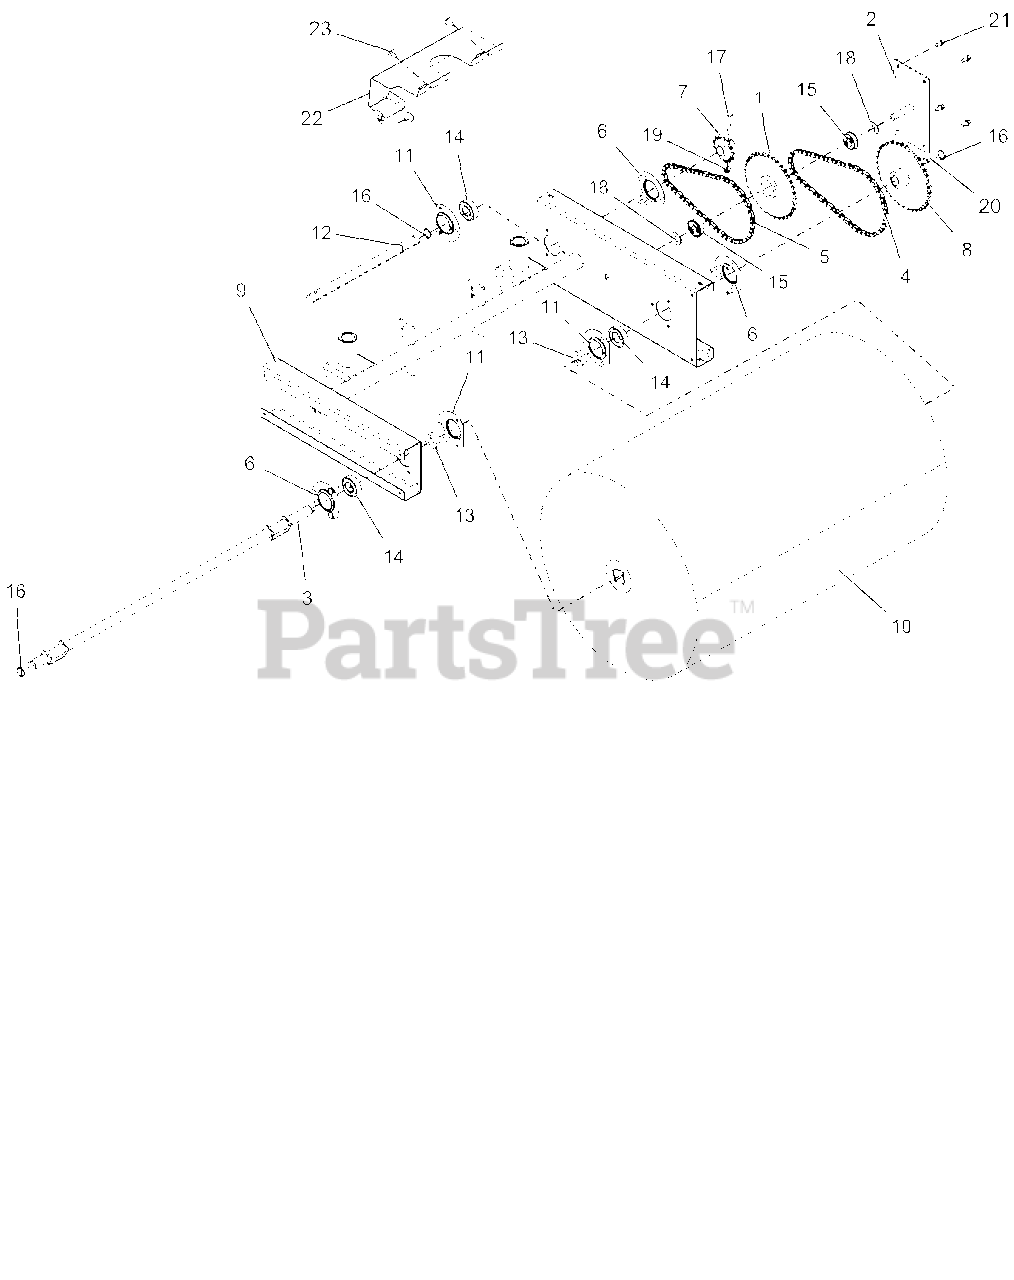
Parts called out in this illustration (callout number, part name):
1	SPROCKET, REDUCTION IDLER
2	PLATE, IDLER REDUCTION MOUNT
3	SHAFT, 28" BRUSH
4	CHAIN, #40-54 LINKS
5	CHAIN, #41-50 LINKS
6	BEARING FLANGE
7	SPROCKET, DRIVE
8	SPROCKET, DRIVEN
9	FRAME, POWER BROOM-DELUXE
10	BRUSH, 18"DIA X 28"WIDE
11	BEARING FLANGE
12	SHAFT, TRANSMISSION
13	SPACER .755X1.250X.370
14	BRG-BALL .750X1.750X.50
15	BRG-BALL .50X1.38X.438 SEALED
16	RG-RTNG-EXT .689X.078
17	@BLT-HEX .25-20X1.75 GR5 YWZC
18	WSHR-FL-STL .536X1.07X.109 YZ
19	@NUT-LK-TOP-FLG .25-20 YWZC
20	KEY-WDRF .188X.75X.313 SAE 9
21	SCR-TAP .25-20X.50 HWH TR YWZ
22	COVER, FRONT SHAFT - CE
23	SCR-TAP .25-20X.50 LGHWH TR YZ
